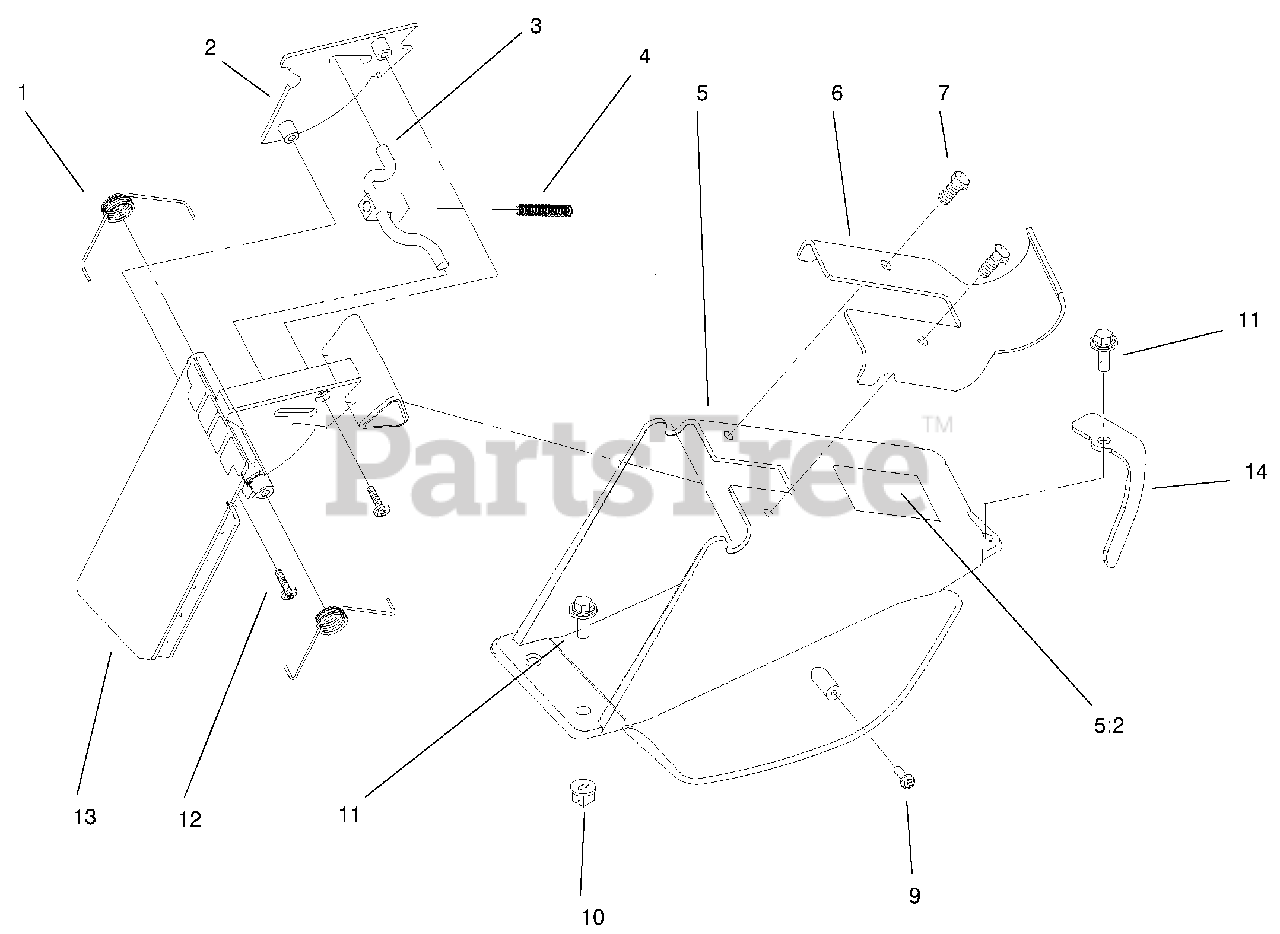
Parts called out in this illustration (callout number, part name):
1	Spring-Door, RH
2	Door Cover
3	Latch-Door
4	Spring-Compression, Latch
5	Discharge Chute ASM
5:2	Decal-Danger
6	Plate-Chute,Discharge
7	Screw-Plastite
9	Screw-PPH
10	Grommet
11	Screw-HWH
13	Door-Discharge
